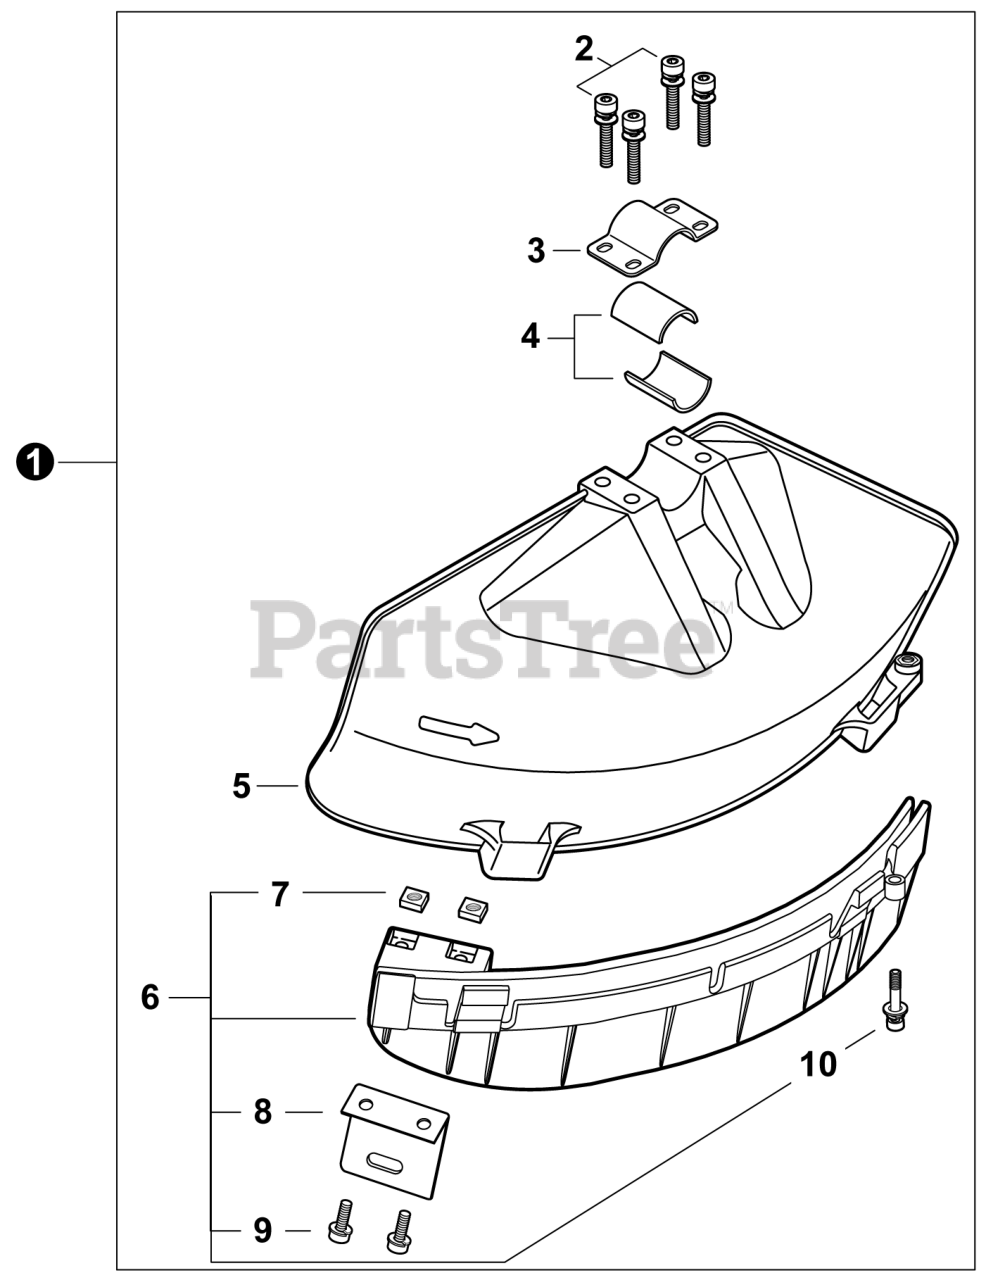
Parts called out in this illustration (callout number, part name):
1	SHIELD KIT, DEBRIS
2	BOLT M5x45
3	CLAMP, UPPER
4	SPACER 24
5	SHIELD, DEBRIS - BLADE
6	EXTENSION ASSY, DEBRIS SHIELD
9	BOLT 5x16
10	BOLT M5x22
